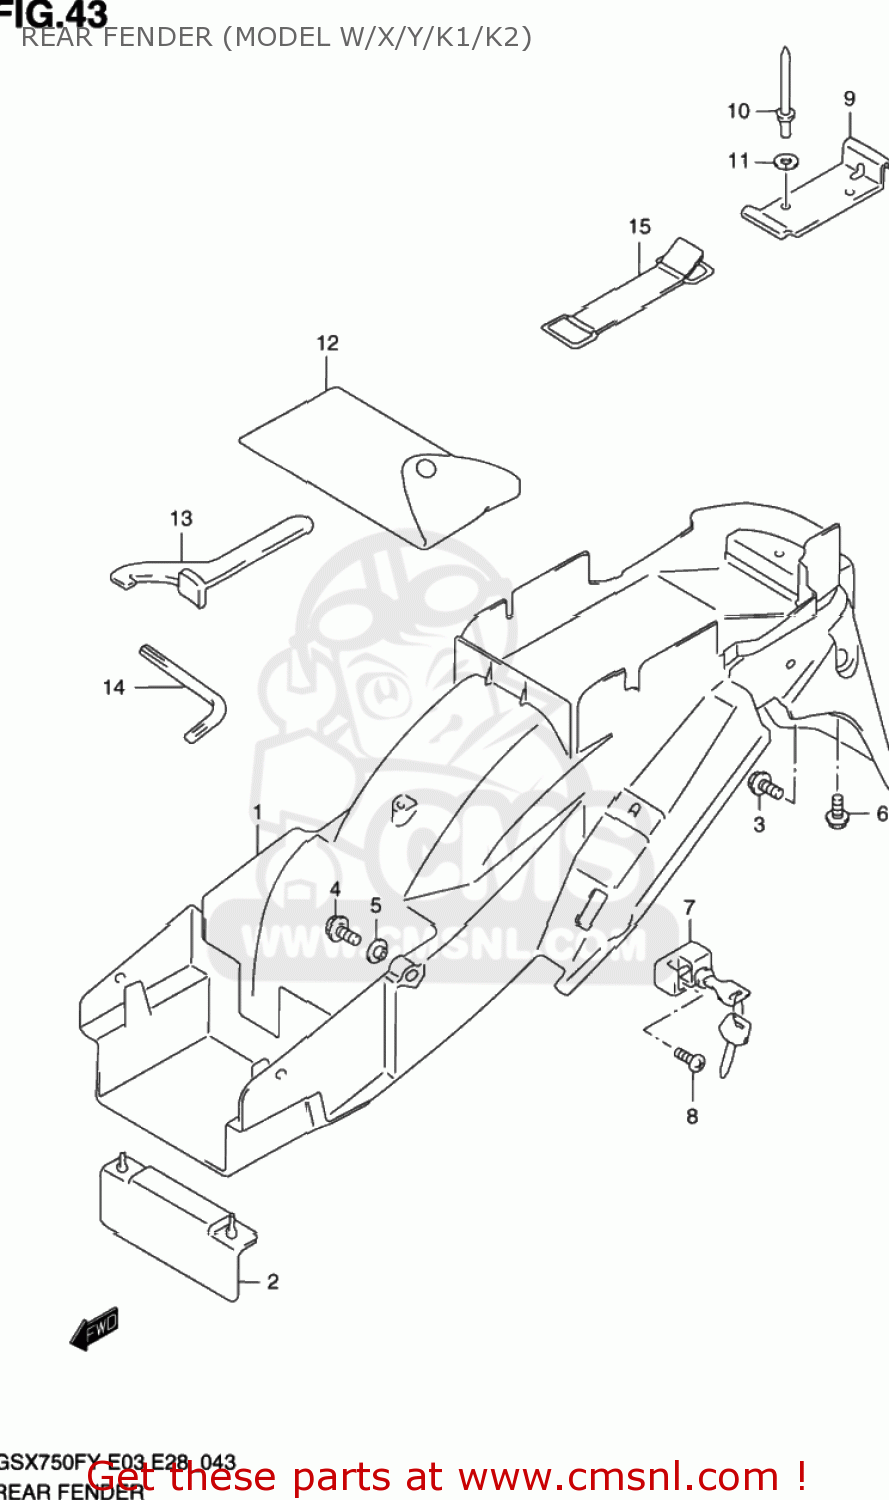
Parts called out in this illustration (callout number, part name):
1	FENDER,RR
2	MUDGUARD,RR FENDER FR
3	BOLT(6X16)
4	BOLT
5	WASHER
6	BOLT 6X16
7	LOCK SET,HELMET
8	SCREW(6X14)
9	HOLDER,TOOL
10	RIVET
11	WASHER
12	TOOL ASSY
13	CLAMP
14	SPANNER,HEXAGON
15	BAND,TOOL
